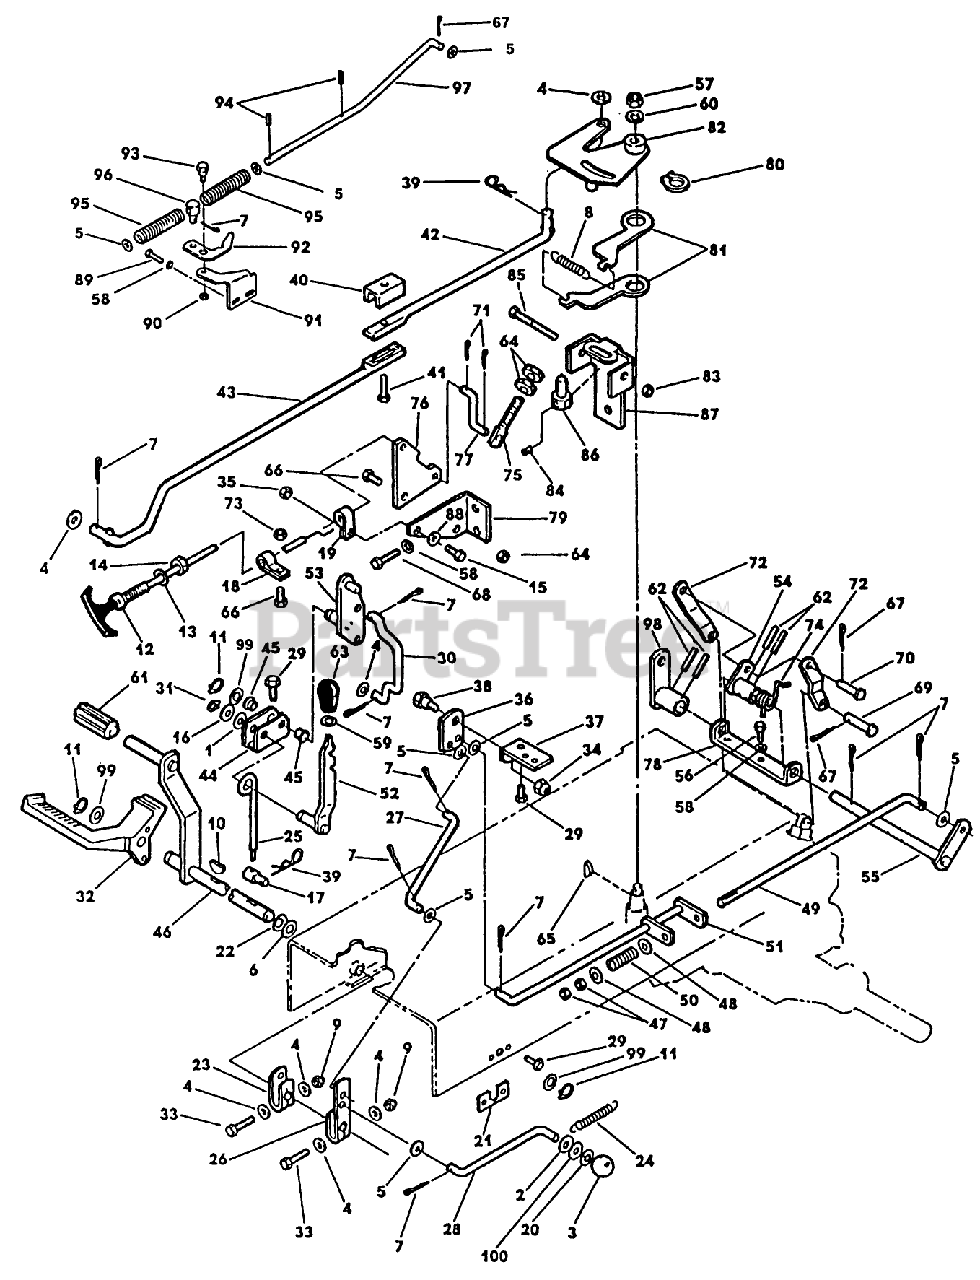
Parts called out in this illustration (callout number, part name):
8	SPRING-EXTENSION
9	NUT-LOCKING
14	Nut, Hex Jam
22	WASHER-CUPPED
31	RING - RETAINING
37	BRKT-BRAKE PIVOT
39	PIN-HAIR
50	SPRING-BRAKE
52	CRUISE RELEASE AY.
56	SCREW - HEX
68	SCREW-THD ROLL, HWH
73	NUT-LOCK, CONE
74	SPRING,TORSION
76	LEVEL - PIVOT
79	BRACKET,CABLE
80	RING - RETAINING
84	SETSCREW
91	BRACKET-LOCK
93	BOLT-SHOULDER
